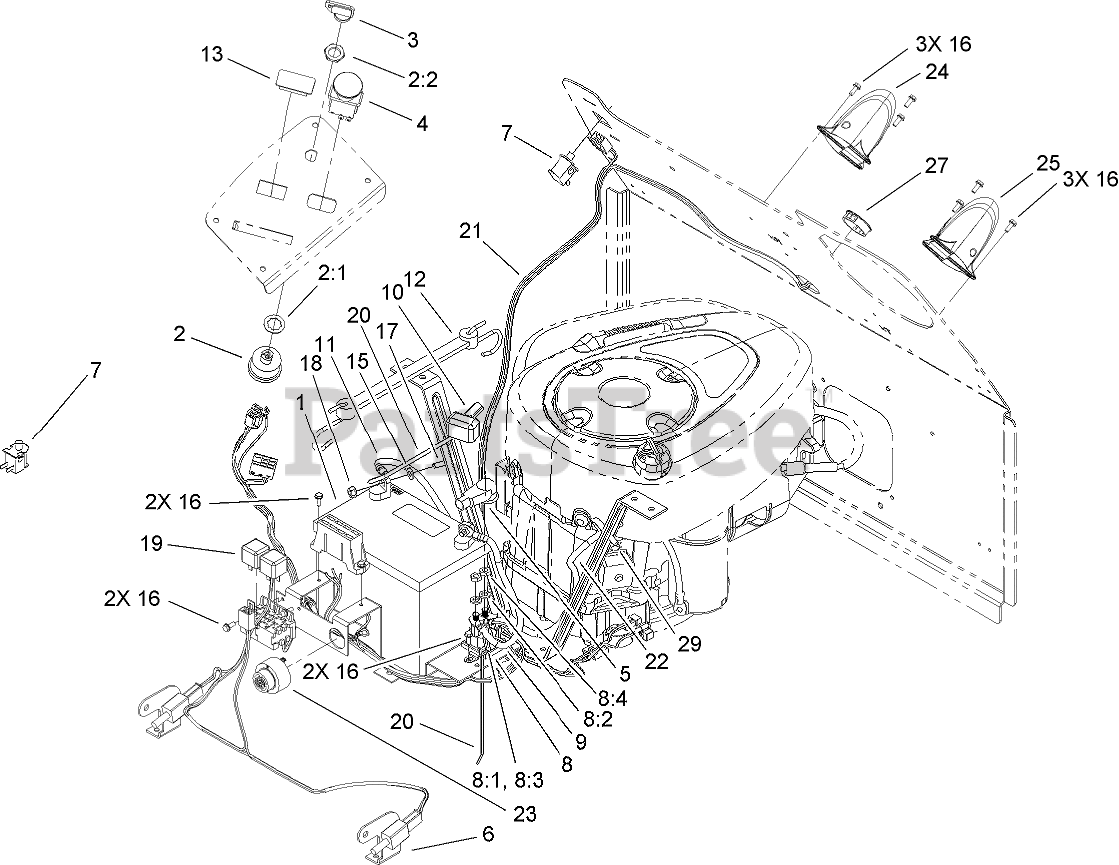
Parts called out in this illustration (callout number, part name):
1	BATTERY
2	Key Switch ASM
2:1	WASHER-TOOTH, INTERNAL
2:2	NUT-HH
3	KEY-IGNITION
4	SWITCH-PTO
5	BOOT-TERMINAL
6	SWITCH
7	SWITCH-BAIL
8	SWITCH-SOLENOID
8:1	WASHER-LOCK
8:2	WASHER-LOCK
8:3	NUT-HEX
8:4	NUT-JAM
9	CABLE-BATTERY, POSITIVE
10	BOOT-INSULATOR, TERMINAL
11	CABLE-NEGATIVE, BLACK
12	HOLDDOWN-BATTERY
13	PLUG-HOLE
15	WASHER-FLAT
16	SCREW-TAPTITE
17	SCREW-HH
18	NUT-HF
19	RELAY
20	TIE-CABLE
21	HARNESS-DIRECT COLLECT
22	WIRE-21 INCH
23	ALARM-TONE, DUAL
24	BAG SENSOR ASM
25	BAG SENSOR ASM
27	BUSHING-HARNESS, WIRE
29	CLAMP-HOSE
